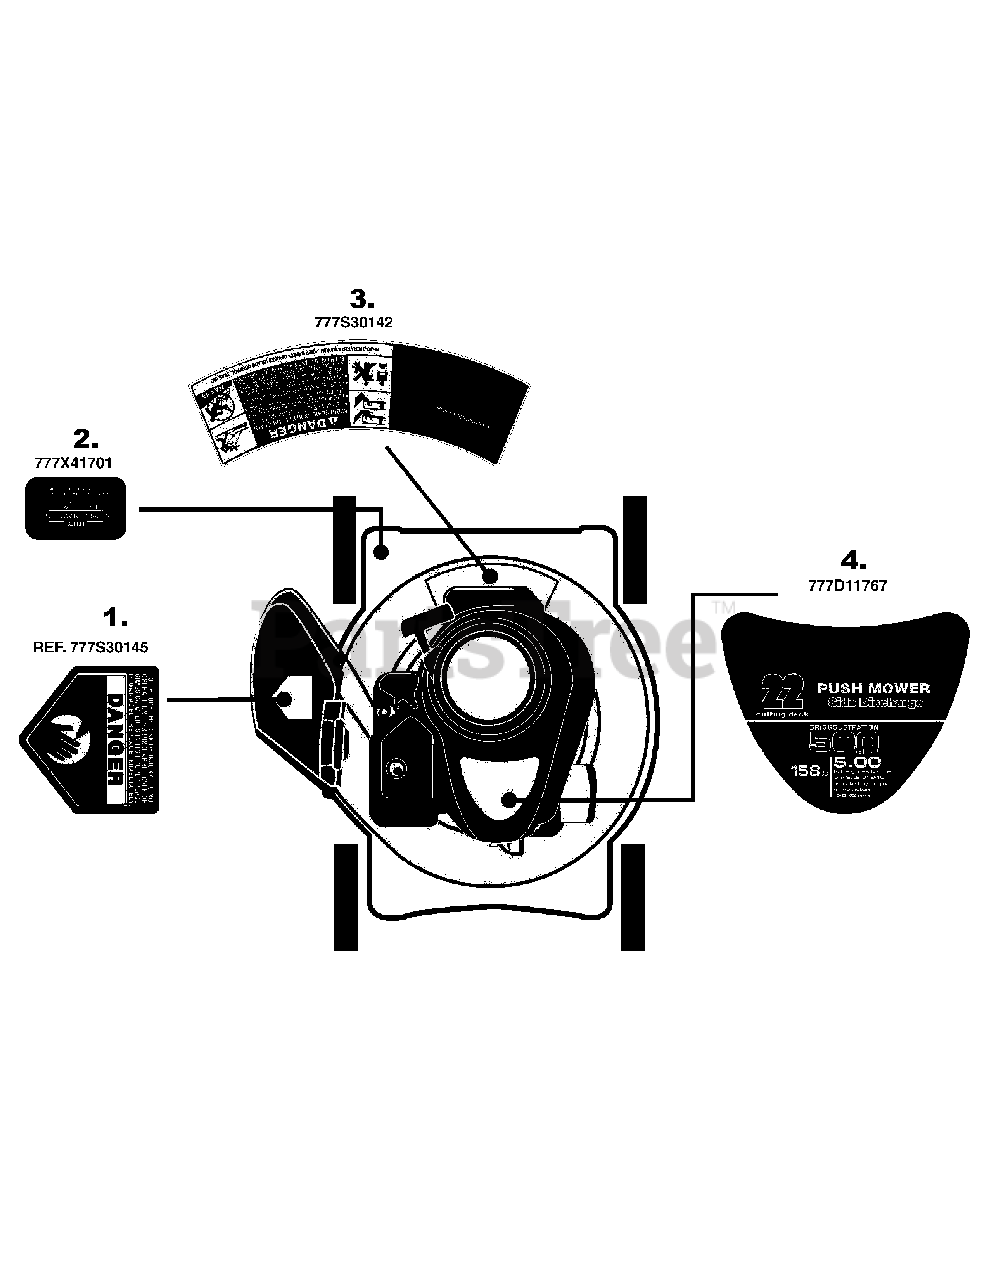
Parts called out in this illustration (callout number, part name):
1	LABEL
3	LABEL-DANGER CURVE
4	LABEL-EDGER SHROUD BOLENS
